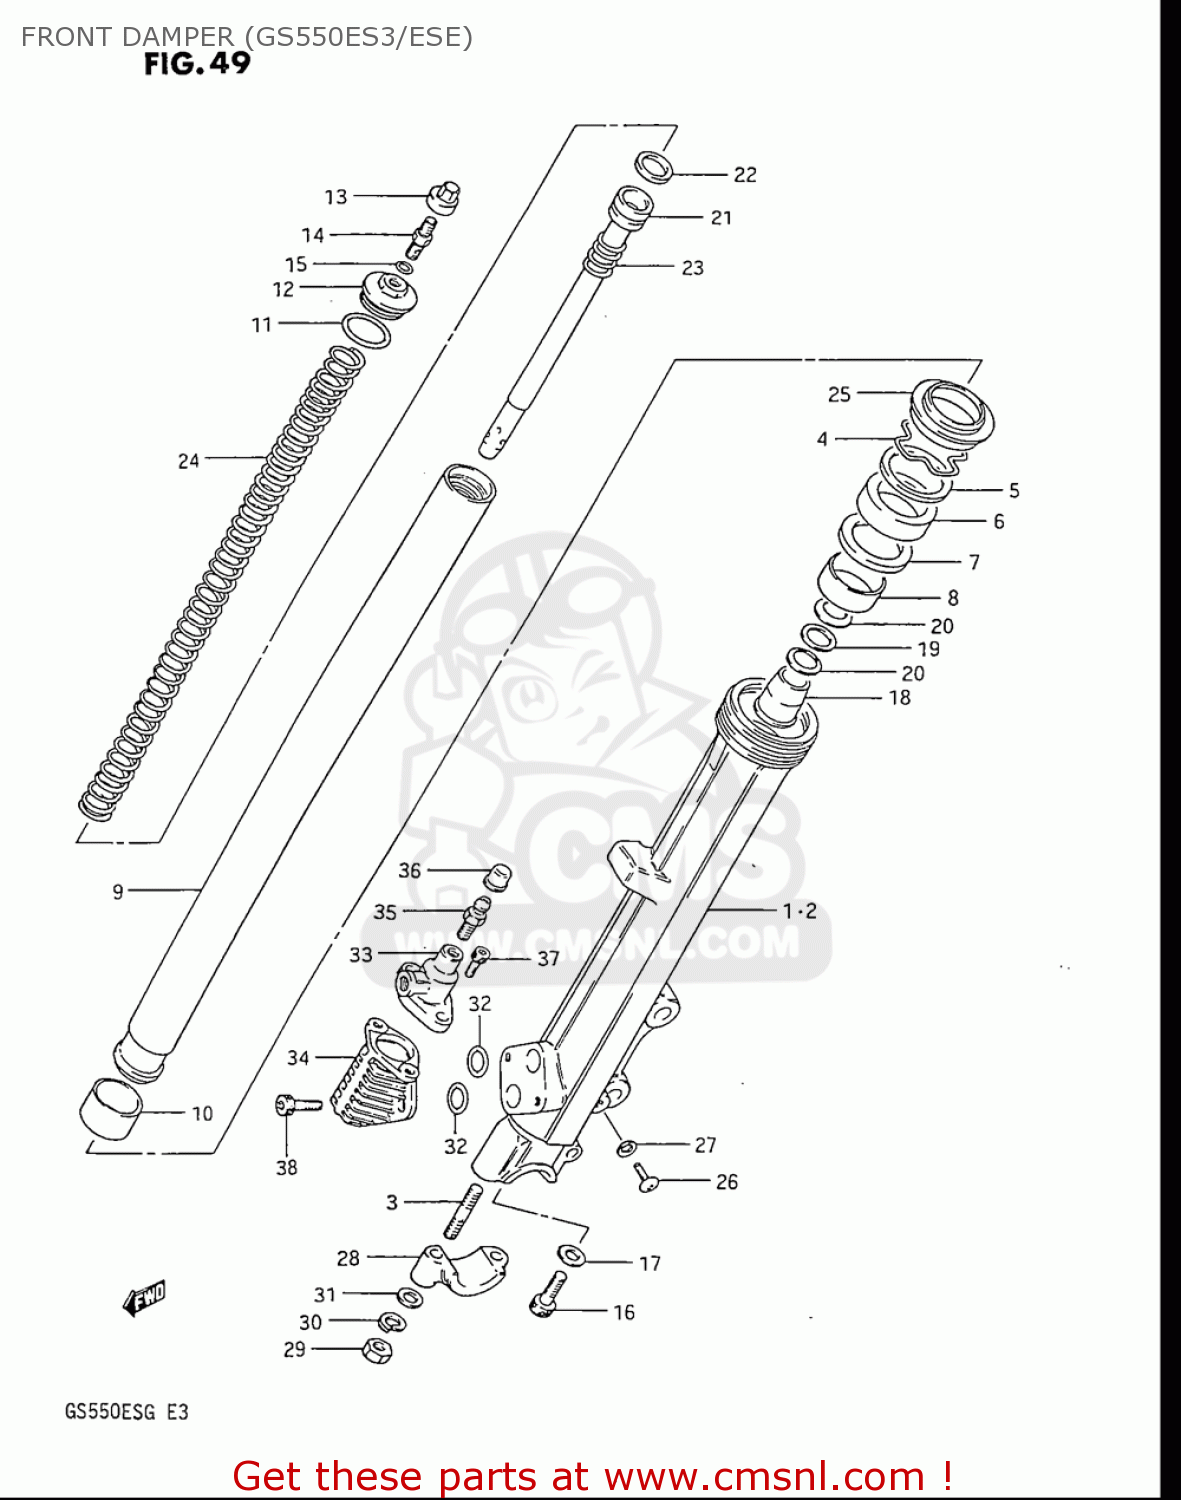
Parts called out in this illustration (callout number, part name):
3	STUD 8X30
4	RING,STOPPER
5	WASHER. FRONT FORK
6	SEAL,OIL
7	WASHER
8	METAL,SLIDE
9	TUBE,FORK,INNER
10	METAL,FR FORK PISTON
11	O RING
12	CAP
13	CAP,FRONT FORK AIR VALVE
14	VALVE ASSEMBLY,REAR CUSHION
15	O RING(D:1.9,ID:5.7)
16	BOLT,FORK CYLINDER(10X25)
17	GASKET (NAS)
18	PIECE,OIL LOCK
19	WASHER
20	SPRING,LEAF
22	RING,PISTON
25	SEAL,DUST
26	SCREW
27	GASKET,DRAIN,PLUG (NAS)
29	NUT
30	WASHER,LOCK
31	WASHER
32	O RING(D:2.4,ID:11.8)
34	VALVE SET,MODULATOR
35	BREATHER,AIR
36	CAP,BLEEDER PLUG
38	BOLT
